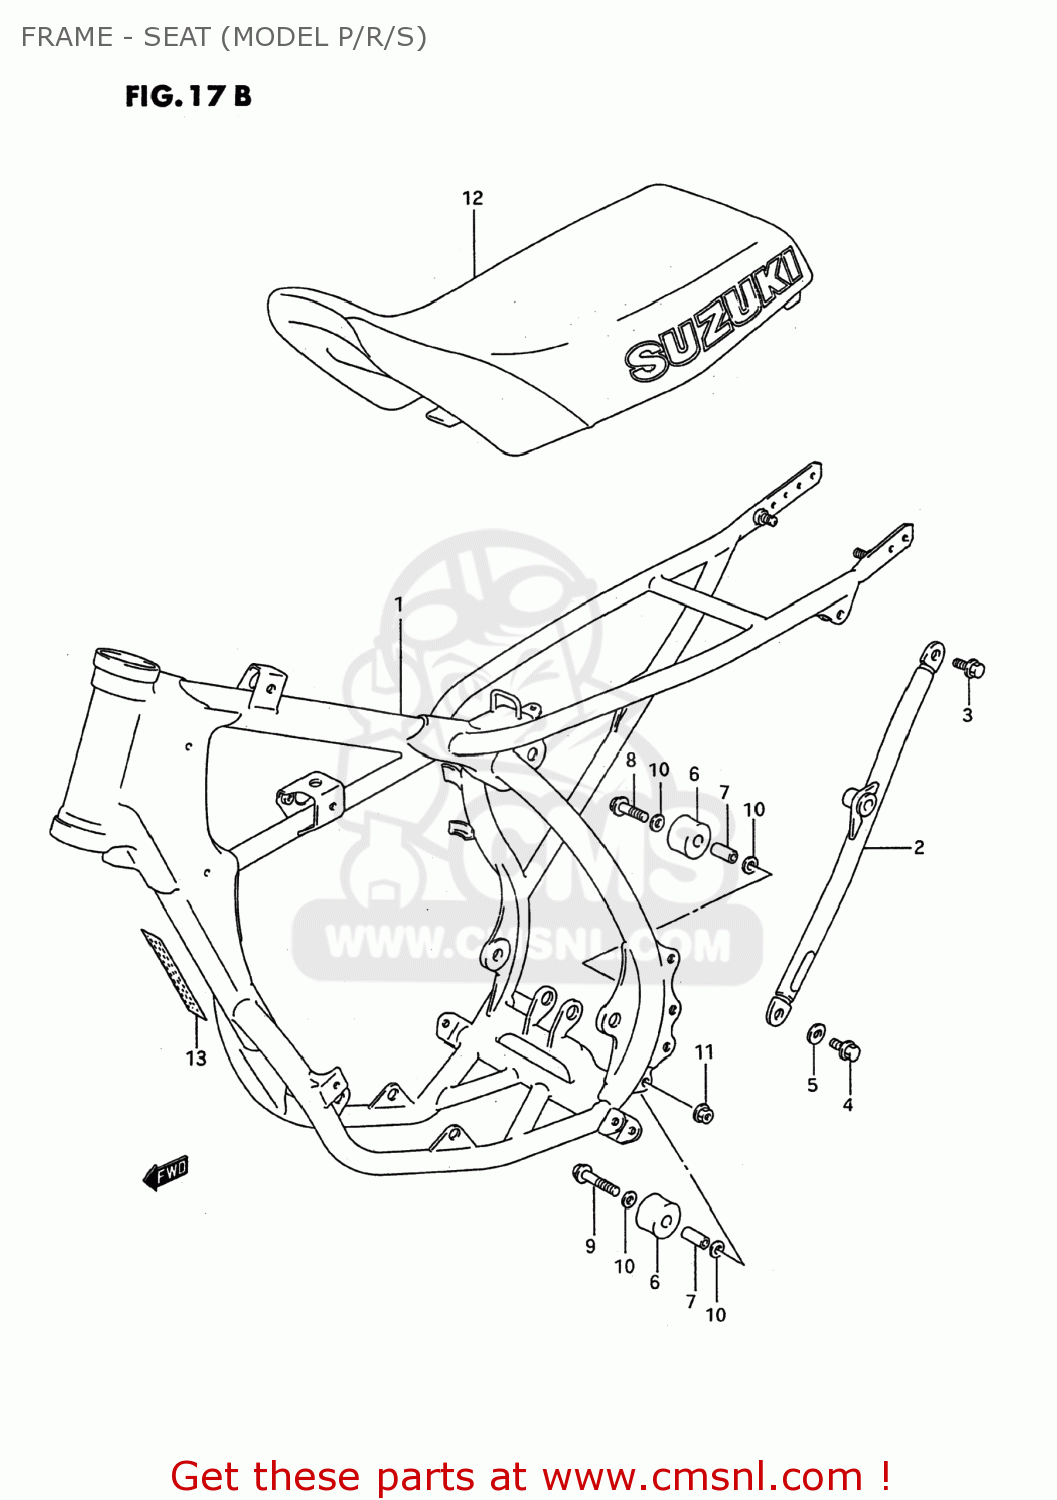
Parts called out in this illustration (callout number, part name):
1	FRAME
2	TUBE,FRAME SIDE(CHARCOAL)
3	BOLT(8X22)
4	BOLT(8X16)
5	WASHER
6	ROLLER,CHAIN CONTROL
7	SPACER(8.6X12X25.5)
8	BOLT(8X41)
9	BOLT
10	WASHER
11	NUT
12	SEAT SET
13	PLATE,WARNING
